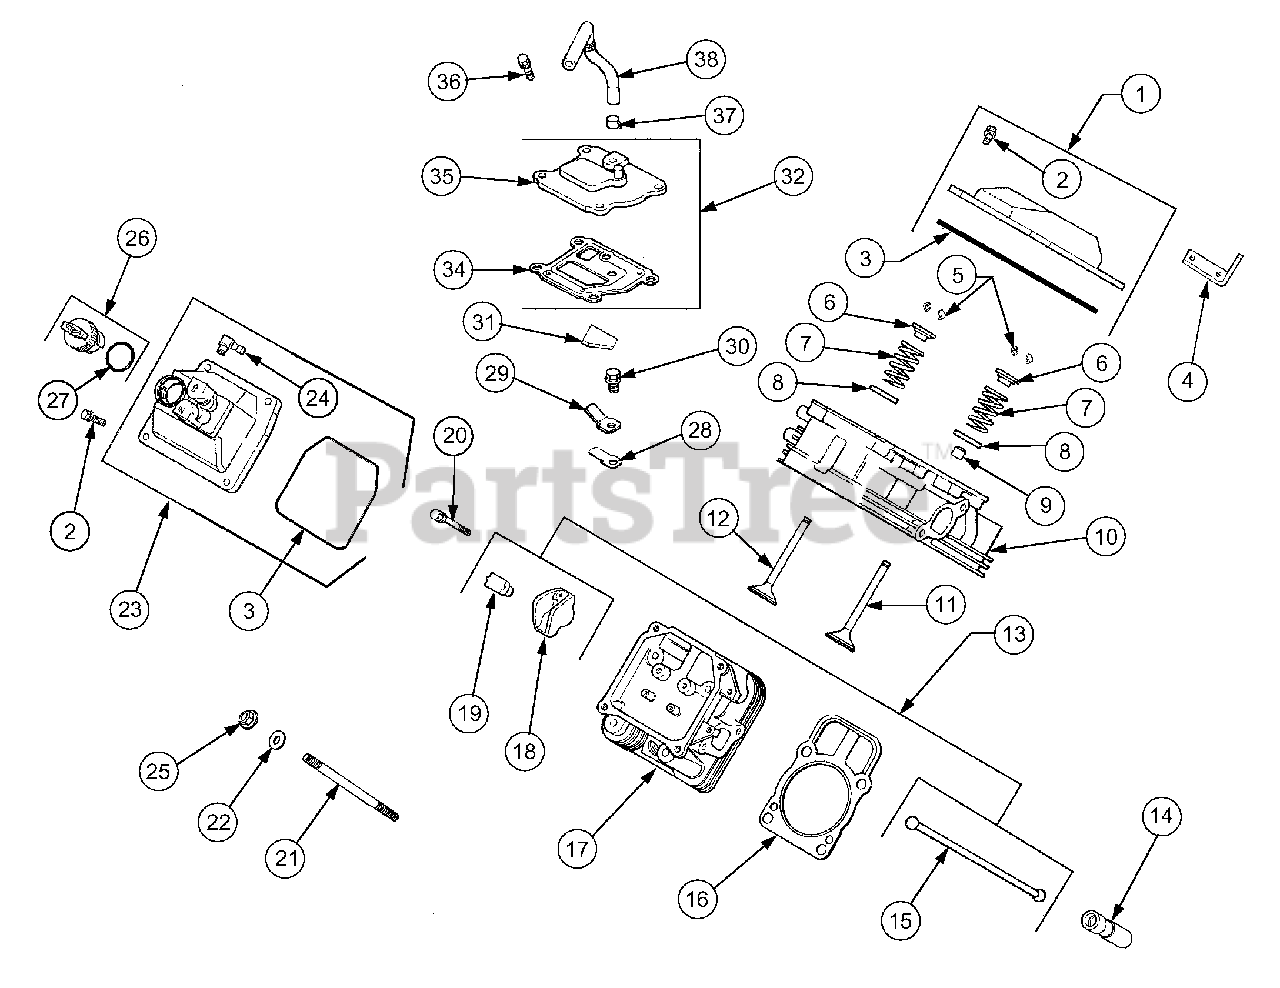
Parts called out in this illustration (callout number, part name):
1	Kit, Valve Cover
2	Screw, Shoulder
3	O-Ring, Valve Cover
4	Strap, Lifting
5	Kit, Retainer
6	Cap, Valve Spring
7	Spring, Valve
8	Retainer, Spring
9	Seal, Valve Stem
10	Kit, Cylinder Head #1
11	Valve, Intake Std
12	Valve, Exhaust Std
13	Kit, Valve Train
14	Lifter, Valve
16	Kit, Cylinder Head Gasket
17	Kit, Cylinder Head #2
19	Pivot, Rocker Arm
20	Screw, Hex Flng, M6 x 1.0 x 34
21	Stud, Cylinder Head
23	Cover Kit, Fuel Pump Valve
24	Connector, 90°
25	Nut, Hex Flange, M8 x 1.25
26	Cap Assembly, Oil Fill
27	O-Ring
28	Reed, Breather
29	Retainer, Breather Reed
30	Screw, Hex Flng, M5 x 0.8 x 10
31	Filter, Breather
32	Kit, Breather
34	Gasket, Breather
35	Cover, Breather
36	Screw, Hex Flng M6 x 1.0 x 20
37	Clamp, Breather
38	Hose, Breather
